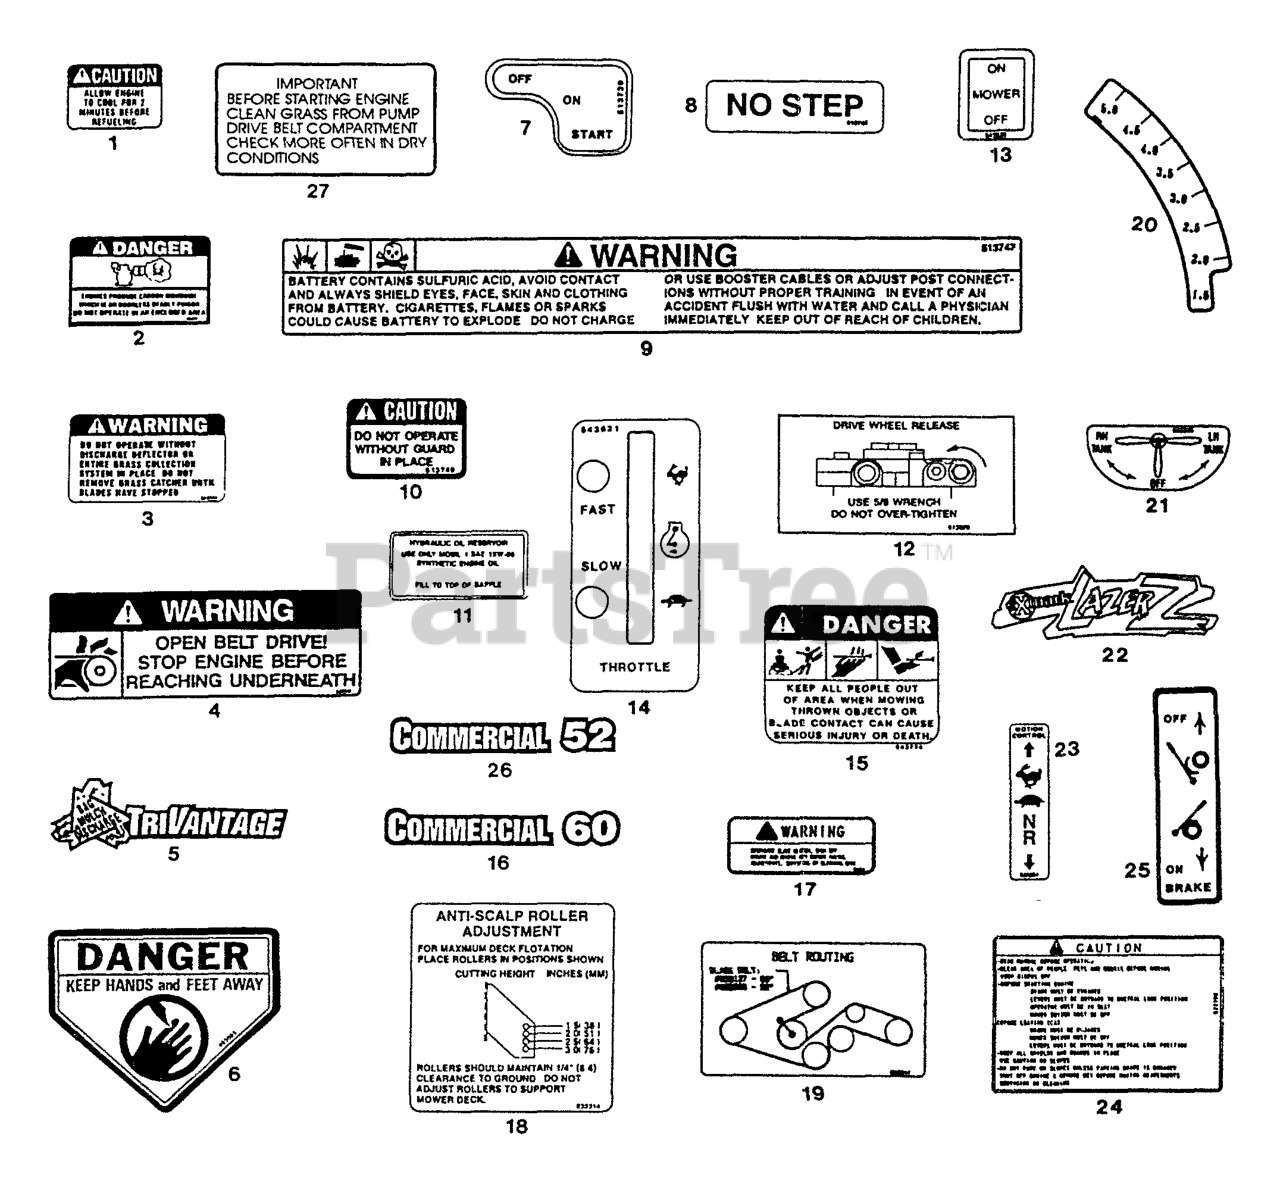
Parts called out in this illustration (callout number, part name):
3	DECAL-WARNING, DISCHARGE
4	DECAL,BELT DRIVE
6	DECAL-DANGER
8	DECAL,NO STEP
9	DECAL-BATTERY
10	DECAL-GUARD
11	DECAL,HYD TANK
13	DECAL-MOWER SWITCH
15	DECAL-DANGER
16	DECAL,COMMERCIAL 60
17	DECAL,WARNING
20	DECAL-HEIGHT, DECK
25	DECAL-LAZERZ BRAKE
26	DECAL,COMMERCIAL 52
27	DECAL-IMPORTANT
